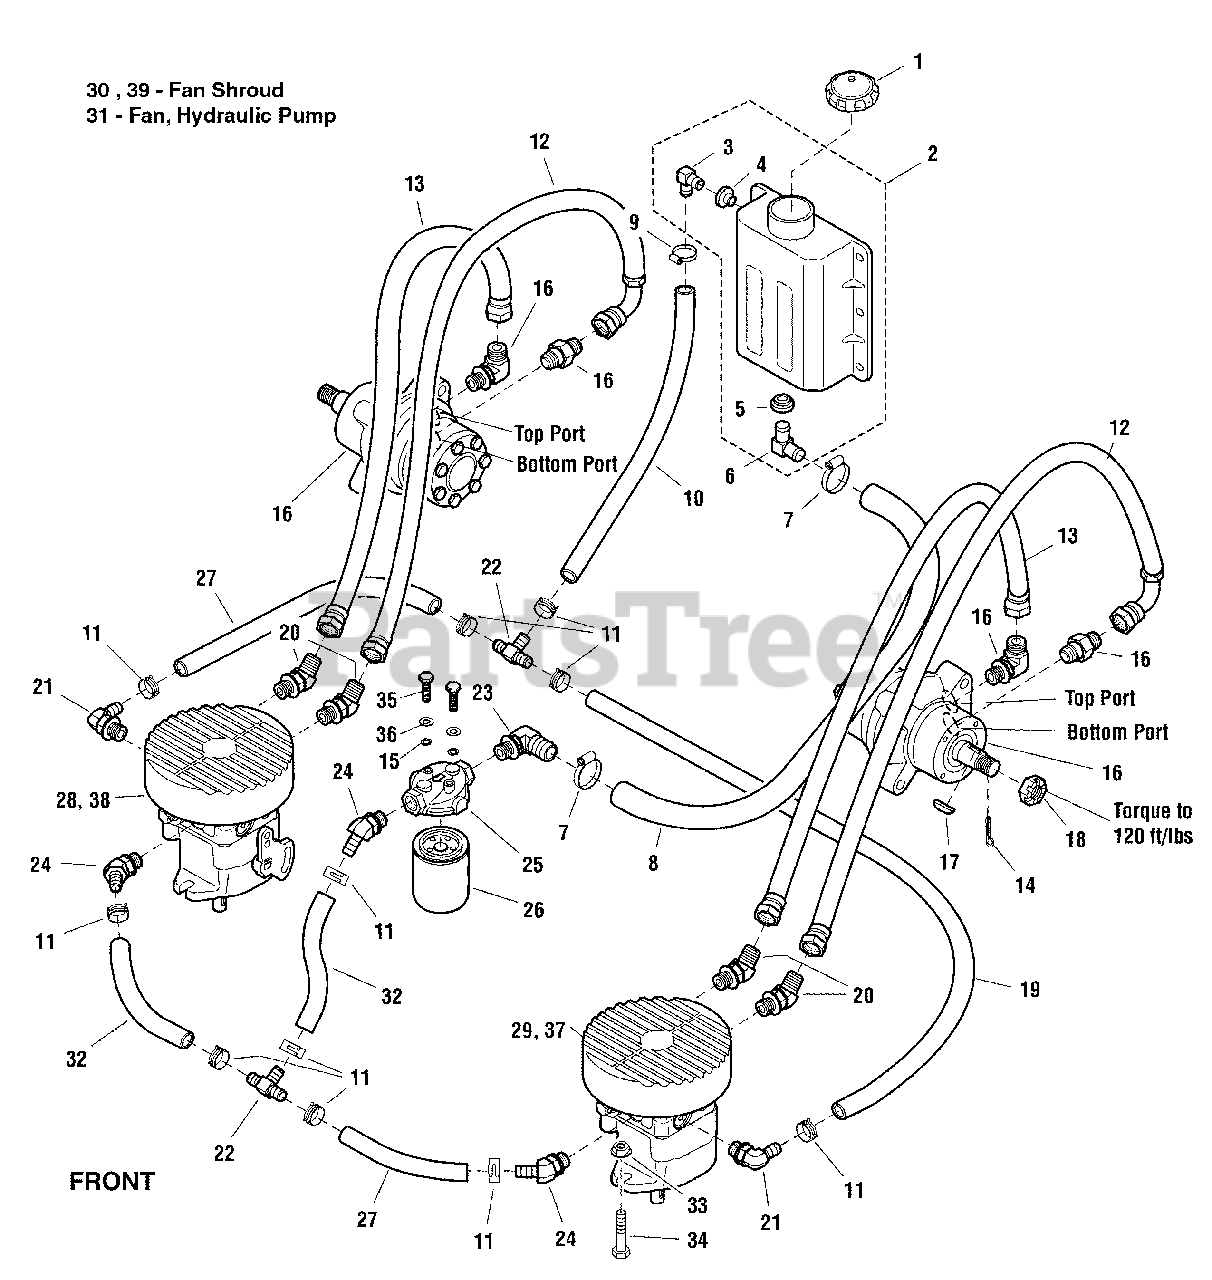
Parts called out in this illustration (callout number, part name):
1	CAP, Hydraulic Oil Only
2	HYDRAULIC OIL RESERVOIR, Complete
3	FITTING, Elbow, 3/8"
4	GROMMET
6	FITTING, Elbow, 5/8"
7	CLAMP, #10 Hose
8	HOSE, Hydraulic, 24.5"
9	CLAMP, #4 Hose
10	HOSE, Hydraulic, 18.5"
11	CLAMP, Hose
12	HYDRAULIC HOSE ASSEMBLY, 25"
13	HYDRAULIC HOSE ASSEMBLY, 21"
15	WASHER, 1/4 SAE (5025154)
19	HOSE, Hydraulic, 18"
20	FITTING, O-Ring, 45 Deg.
21	FITTING, O-Ring, 90 Deg.
22	FITTING, TEE, 3/8" Hose
23	FITTING, O-Ring, 90 Deg.
24	FITTING, O-Ring, 45 Deg.
25	FILTER HEAD
26	FILTER
27	HOSE, Hydraulic, 6-1/2"
28	HYDRAULIC PUMP, RH
29	HYDRAULIC PUMP, LH
30	FAN SHROUD
31	FAN, HYD. PUMP
32	HOSE, Hydraulic, 6"
33	NUT, 3/8-16 Hex Serrated Flange
34	BOLT, 3/8-16 X 1-1/4"
35	BOLT, 1/4"-20 X 3/4"
36	WASHER, 1/4" LOCK
37	HYDRAULIC PUMP, LH
38	HYDRAULIC PUMP, RH
39	FAN SHROUD
